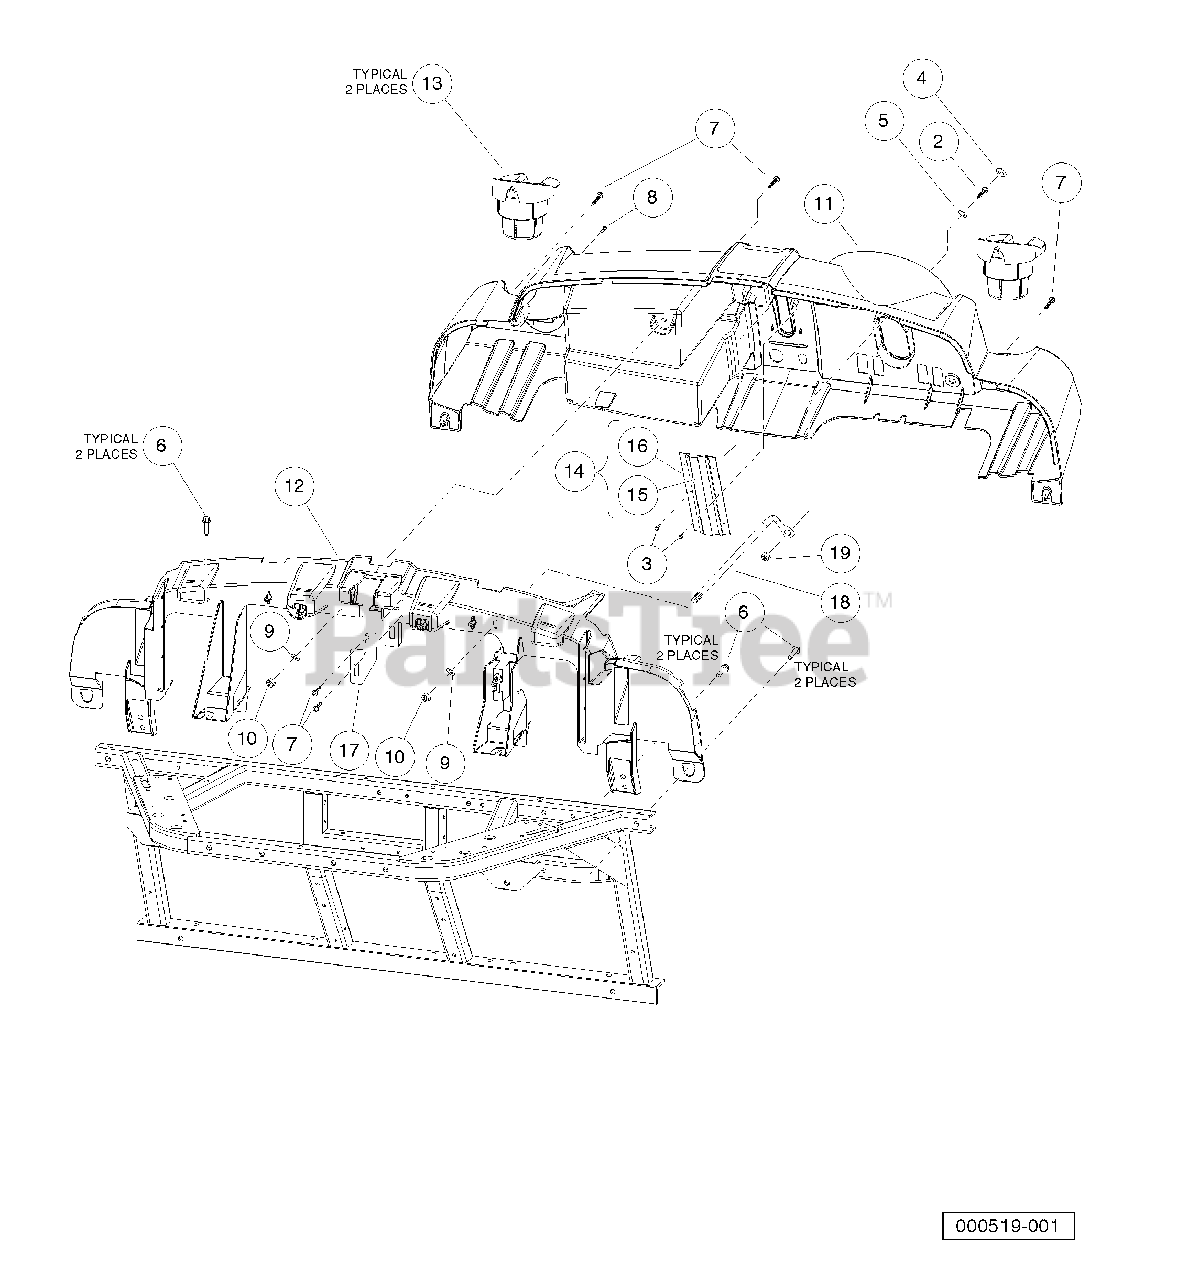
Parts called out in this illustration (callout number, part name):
1	Instl, Dash
2	Screw, 1/4-20 X 1.50 Hex-Head Cap
3	Screw, #8 X 0.500, Hex-Head Hi-Lo
4	Cap, 1/4" Plastic Screw Head
5	Washer, 1/4 Id Scalloped Plast
6	Screw, M8X1.25X30, Hex
7	Screw,m6,torx,interlock,thread
8	M8-1.25 X 80 Sems
9	Washer Hard,m10
10	Lock Nut, Flg M8 X 1.25 Nylon
11	Dash, Design A
12	Support, Structural
13	Cup Holder, Utility
14	Asm, Brush, Fnr
15	Brush, Strip, FNR
16	Holder, Brush, Strip, Fnr
17	Bracket, Hood Support
18	Rod, Connection, Dash
19	Locknut, 1/4-20 Nylon Insert
